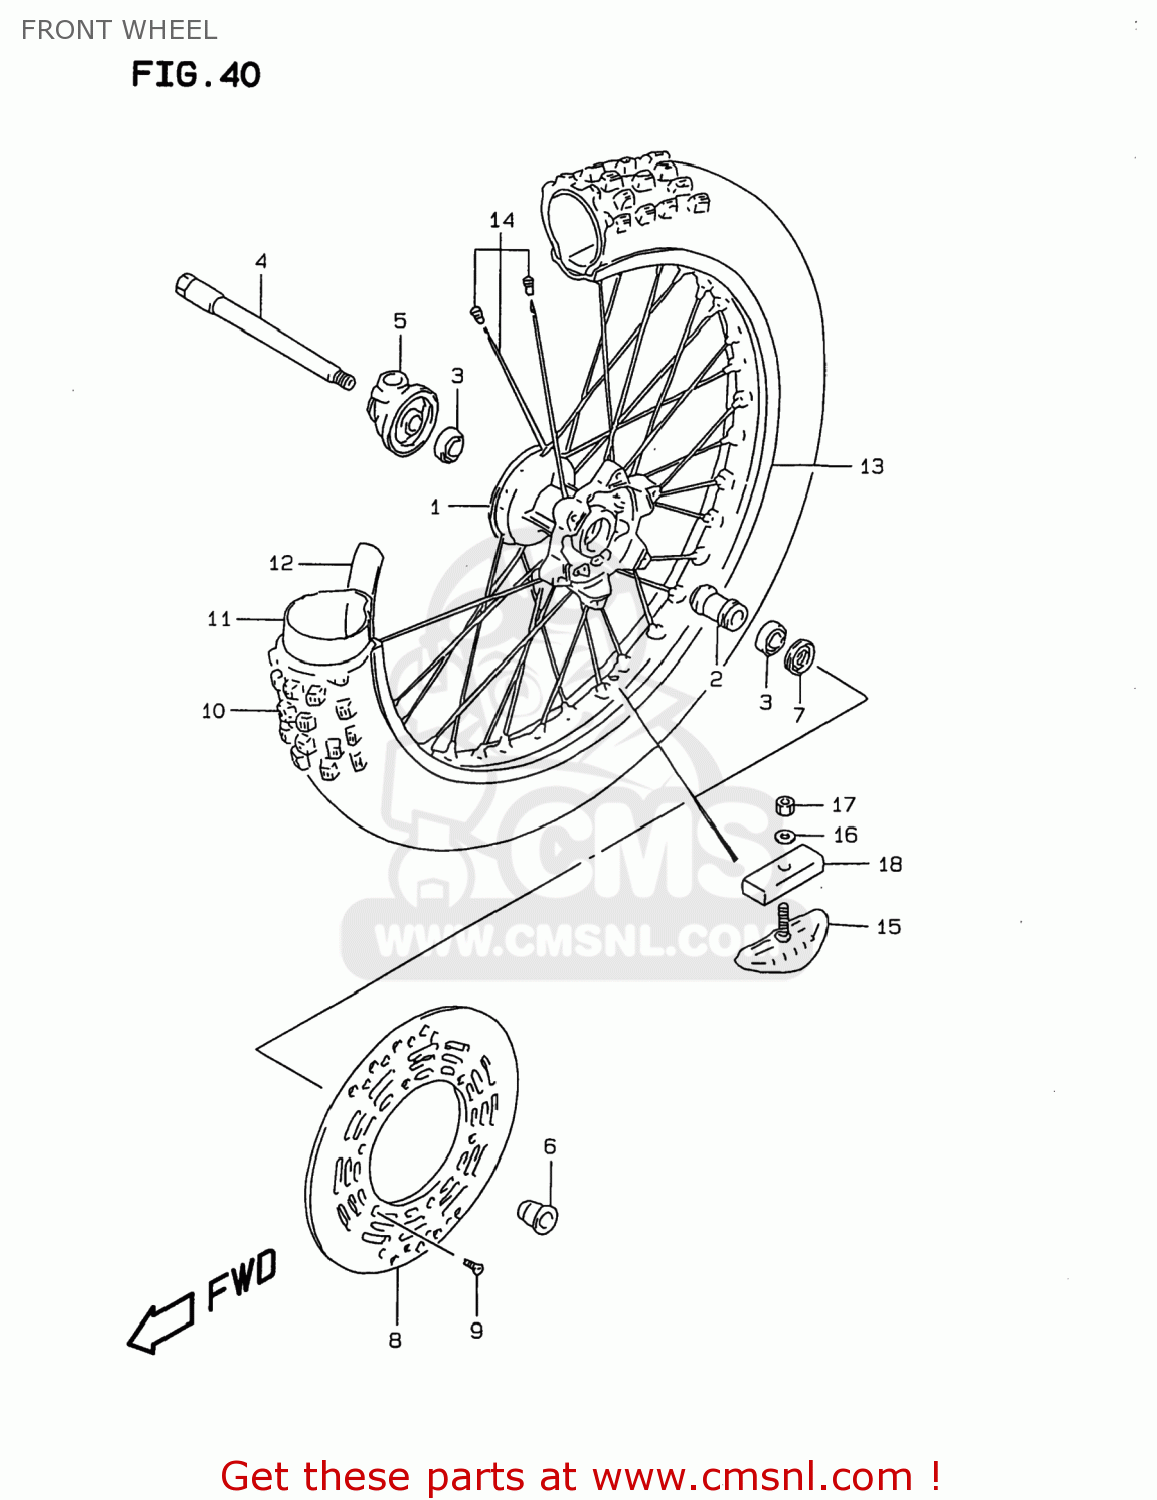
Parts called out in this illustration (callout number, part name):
1	HUB,FR WHEEL
2	SPACER,FR HUB BEARING
3	BEARING
4	AXLE,FR
5	BOX ASSY,SPEEDOMETER GEAR
6	SPACER,FR AXLE,L
7	SEAL,OIL(23X35X6)
8	DISC,FR BRAKE
9	SCREW
10	TIRE COMP,FRONT 80/100-21
11	TUBE
12	PROTECTOR,WHEEL INNER
13	RIM,FRONT WHEEL (1.60X2
14	SPOKE SET,FR WHEEL
15	STOPPER,BEAD
16	WASHER
17	NUT
18	CUSHION,BEAD STOPPER
